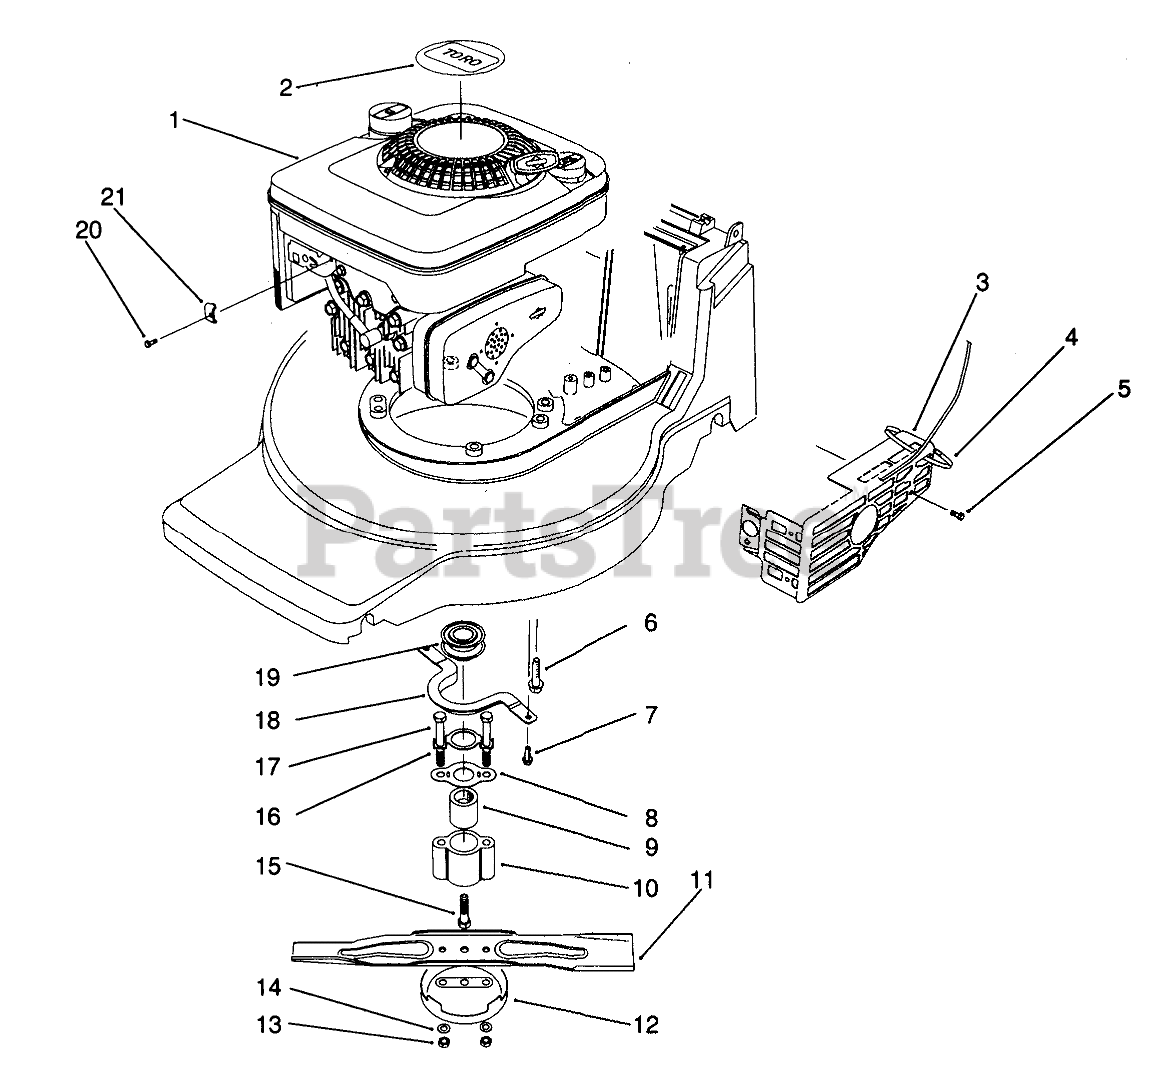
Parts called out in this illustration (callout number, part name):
1	Engine-B&S Quantum
2	DECAL - RECOIL
3	MUFFLER GUARD F/W
4	TIE-CABLE
5	SCREW W/ENGINE
6	3/8-16 X 2 CAPSCREW
7	SCREW-HWH
8	SPRING FRICTION
10	RETAINER
11	Blade-48cm
12	Anti Scalp Cup
13	Nut
14	WASHER
15	SCREW - CRANKSHAFT
16	BLADE RETAINER BRKT
17	SCREW - BLADE
18	Guide-Belt
19	PULLEY-DRIVE, ZONE START
20	Screw
21	CLAMP-CASING
